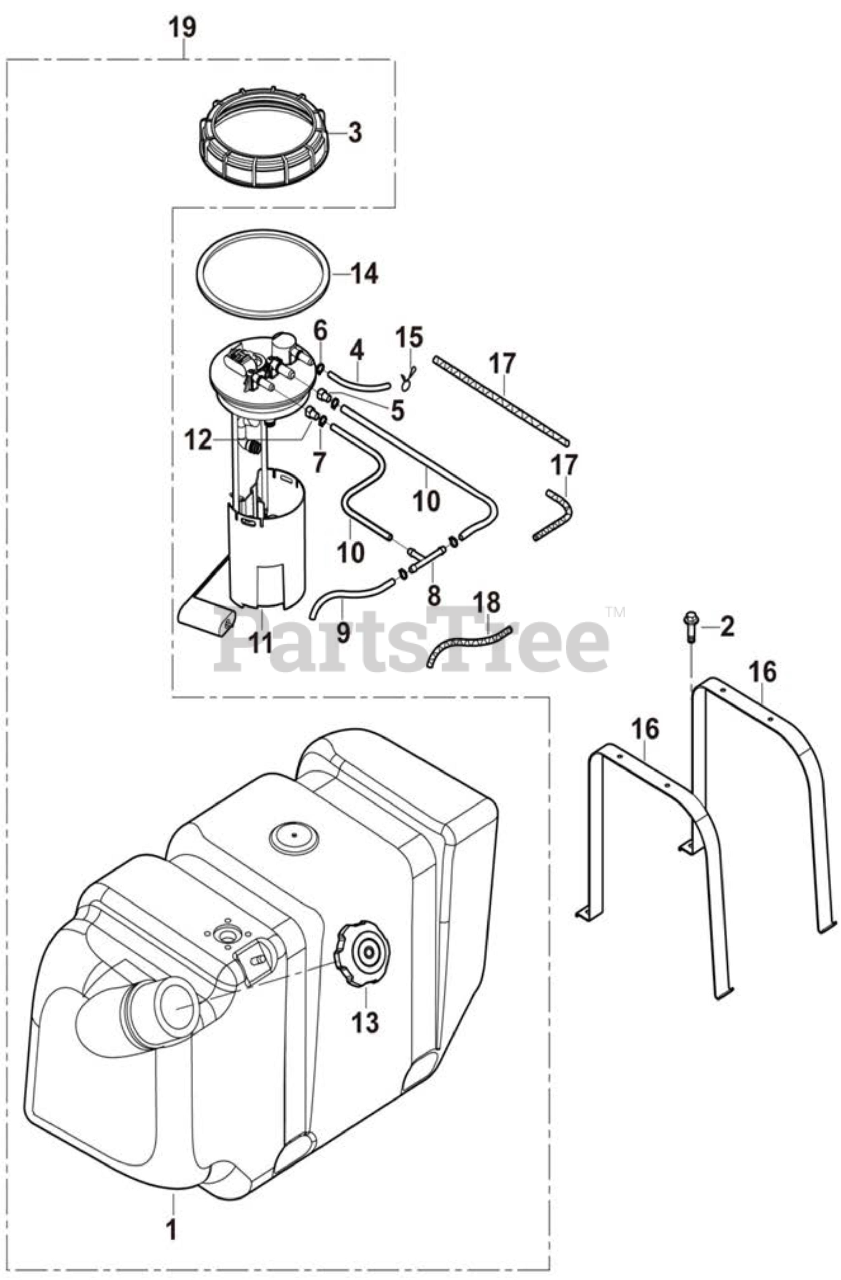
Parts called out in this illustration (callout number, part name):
1	Fuel Tank Body
2	Flange Bolt M8X20
3	Oil pump gland
4	Breather pipe,fuel tank
5	Fuel outlet Plug
6	Spring Clamp E
7	Pressure Clamp A
8	Triplet Joint Fuel Pipe
9	High Pressure Fuel Pipe
10	High Pressure Fuel Pipe II 8X14X885
11	Fuel Pump
12	Fuel Inlet Plug
13	Fuel tank switch cap
14	Seal Gasket B For Fuel Pump
15	Hoop Spring
16	Fuel Tank holddown
17	Thermal insulation bellows,Aluminum Foil
18	Thermal insulation bellows ,Aluminum Foil
19	Fuel Tank Assy.
